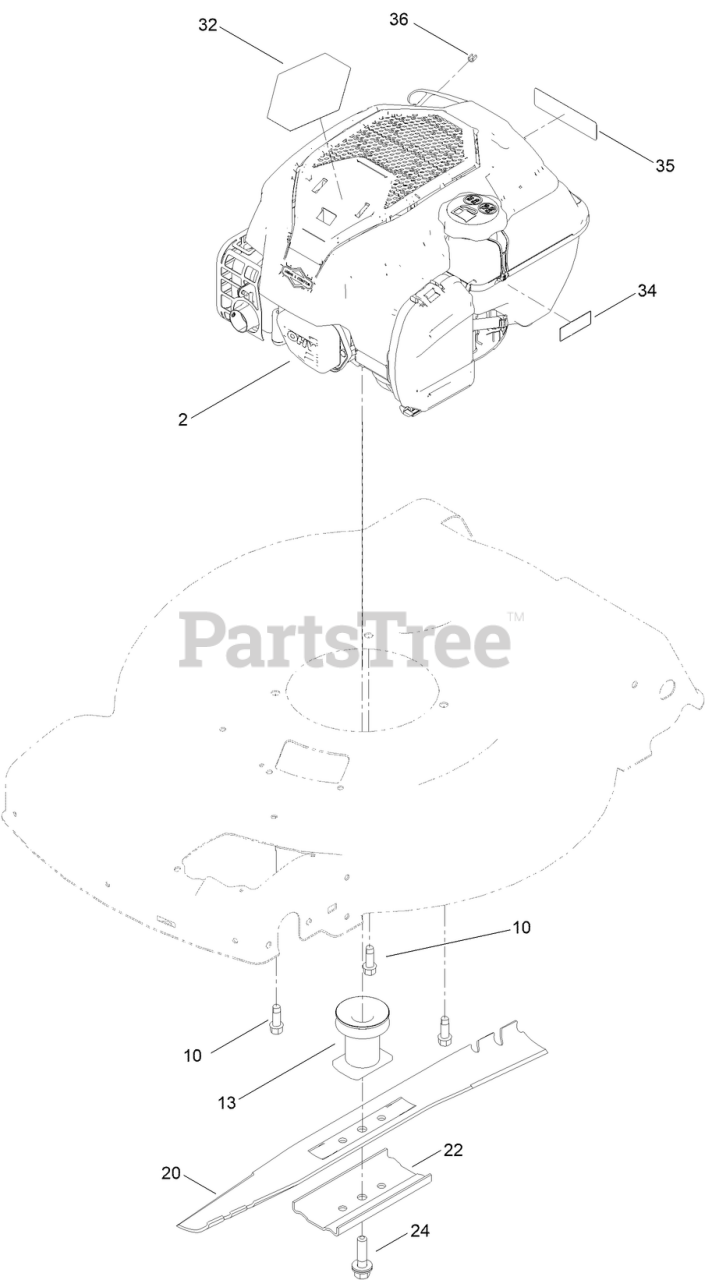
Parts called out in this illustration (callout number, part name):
2	ENGINE-BRIGGS, 625 EXI ZS SS
10	SCREW-TAPTITE
13	DRIVER-BLADE
20	BLADE-22 INCH
22	SUPPORT-BLADE
24	BOLT-BLADE
32	DECAL-BRIGGS 625 EXI SS
34	DECAL-LEVEL, FUEL
35	DECAL-ARRESTOR, SPARK
36	STOP-ROPE
